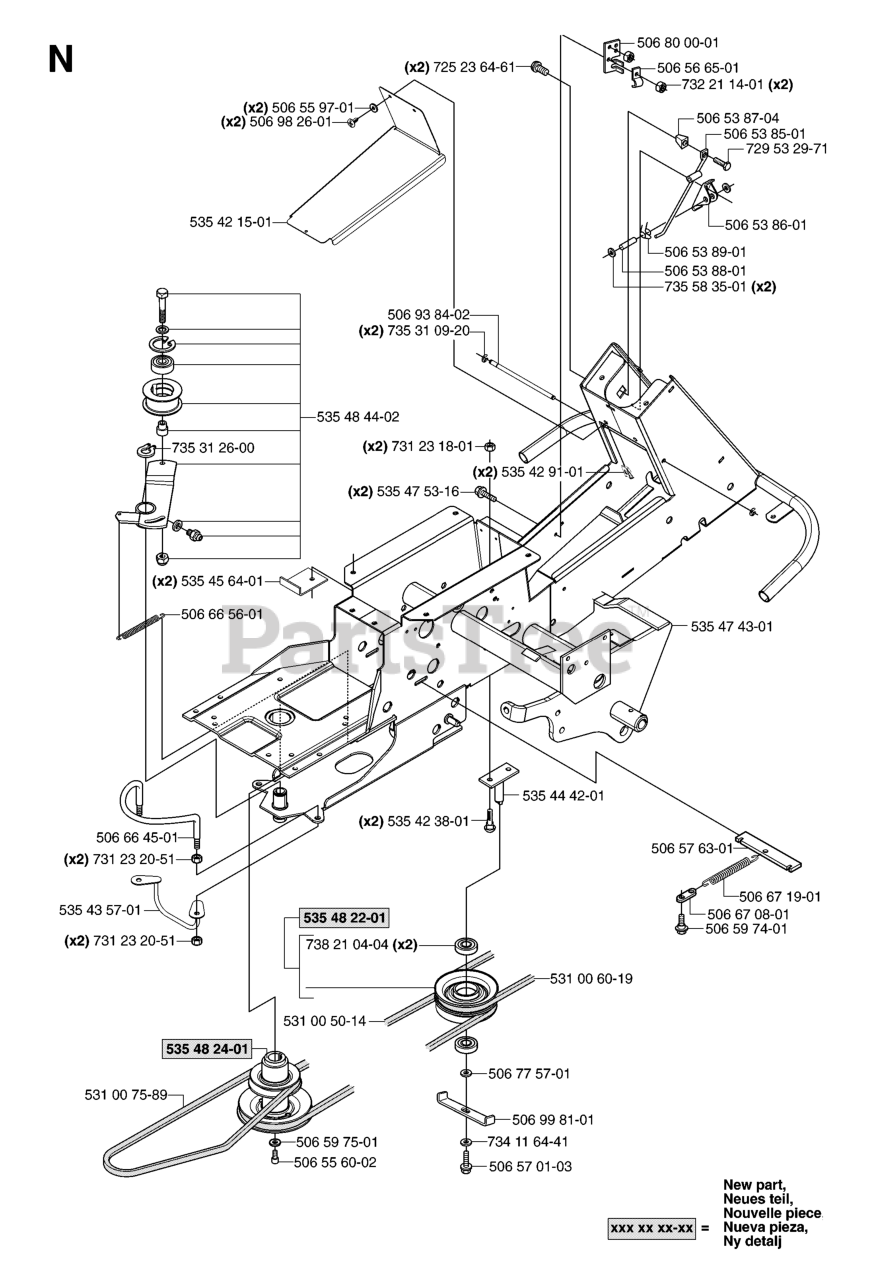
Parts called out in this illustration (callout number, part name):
1	STEERING WHEEL
2	FRONT AXLE ASSY
3	SPINDLE ASM LH
4	SPINDLE ASM RH
5	THRUST WASHER
10	LINK.DRAG.DROPPED.LT
11	WASHER, LOCK 3/8
13	BEARING AXLE
15	NUT-LOC,FLANGE LT
17	SHAFT ASM STEERING
18	THRUST WASHER
19	SHAFT,SUPPORT
20	WASHER
22	SCREW HEX SOCKET 1/4-20 X 5/8
23	SHAFT PITMAN
25	BRACKET STEERING
27	GEAR.SECTOR
29	SCREW
32	ROD ASSY/TIE BALL
36	BUSHING, STEERING
37	SCREW.TT.#10-32X.5.3/8.FLANGE
38	INSERT,STR WHEEL
39	WASHER T
40	GRIPCO NUT
41	ADAPTER LT
42	BOOT, STEERING
44	EXT SHAFT STEERING
46	CAP.SPINDLE.BLACK
47	ZERK M
51	NUT.71038.31-18.HEX.NYLOCK
54	BOLT.5/16-18X1-1/4 FULL.THREAD
62	KIT, STEERING ASSEMBLY
65	SPACER AXLE
66	BEARING ARM
67	Bolt, Hex 5/8 -11 x 2 - 3/4 Gr. 5
68	AXLE, BRACE
74	JOINT
76	TIE ROD
